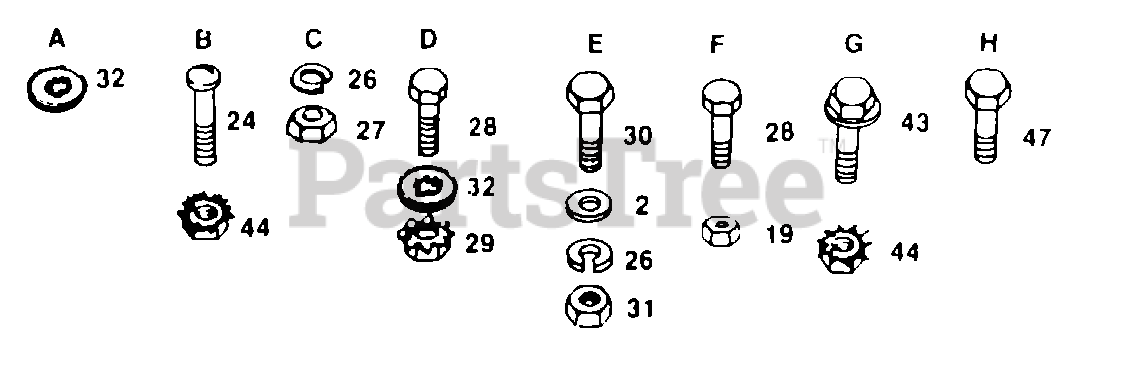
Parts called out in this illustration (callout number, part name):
2	WASHER
26	LOCKWASHER
27	NUT
28	BOLT
29	NUT
30	BOLT LT
43	SCREW
44	"NUT,KEPS"
47	SCREW
